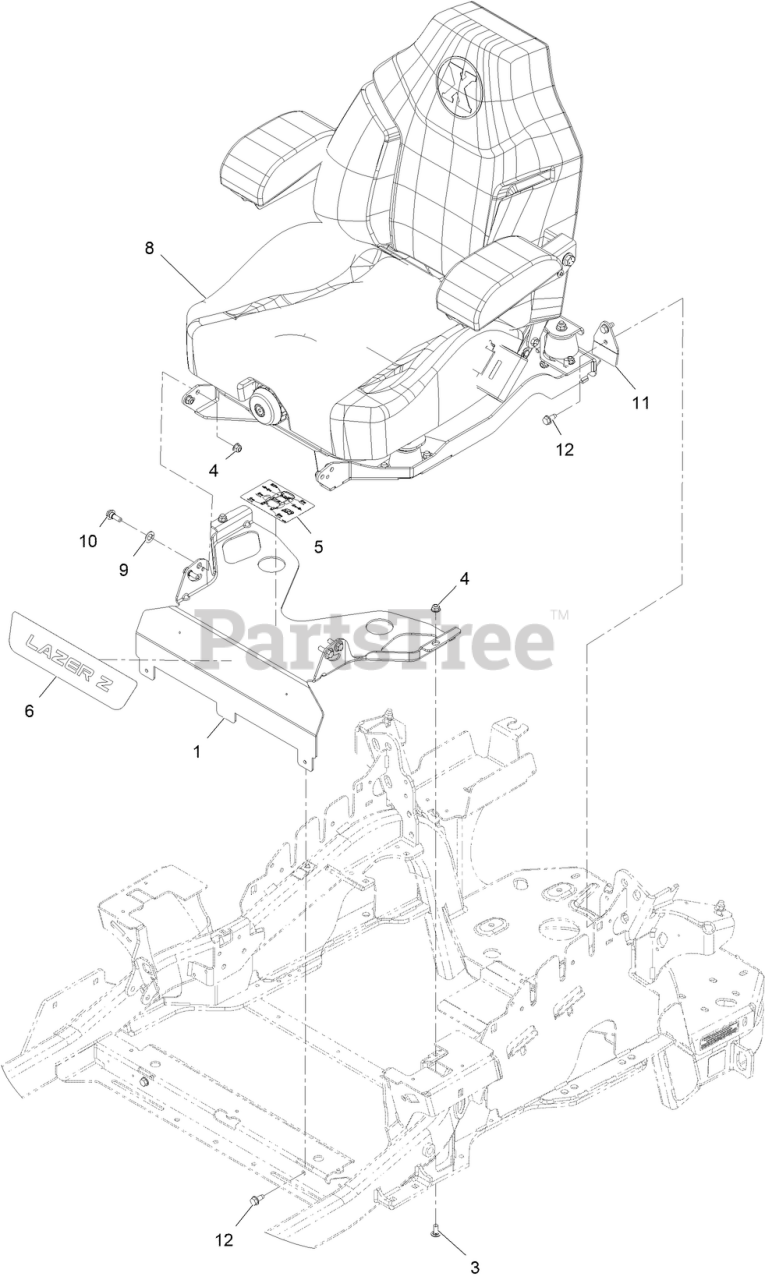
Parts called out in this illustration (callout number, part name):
1	SUPPORT-SEAT
3	SCREW-CARR
4	NUT-HF, NI
5	DECAL-SERVICE AID
6	Decal-Lazer Logo
8	ASM-Seat Suspension
9	WASHER-THRUST
10	SCREW-SHOULDER
11	LATCH-SEAT, UPPER
12	Screw-HWH 5/16-18 X 3/4 Tf
